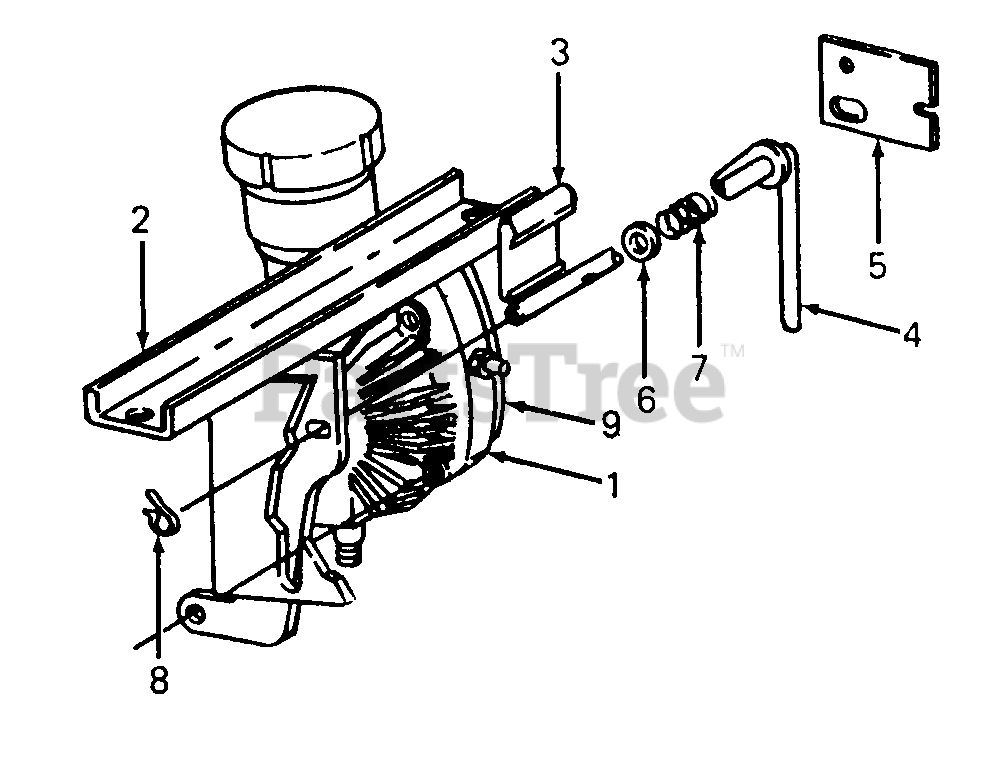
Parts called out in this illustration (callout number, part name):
1	Transmission, Hydro
2	Support, Transaxle
3	Lever, Dump
4	Rod, Dump Valve
5	Bracket, Dump Valve
6	Washer, .344 X .88 X.06
7	Spring, .47 OD X 1.93
8	Pin, 1/2 Int. Cotter
9	Gasket, Hydro Transmission
